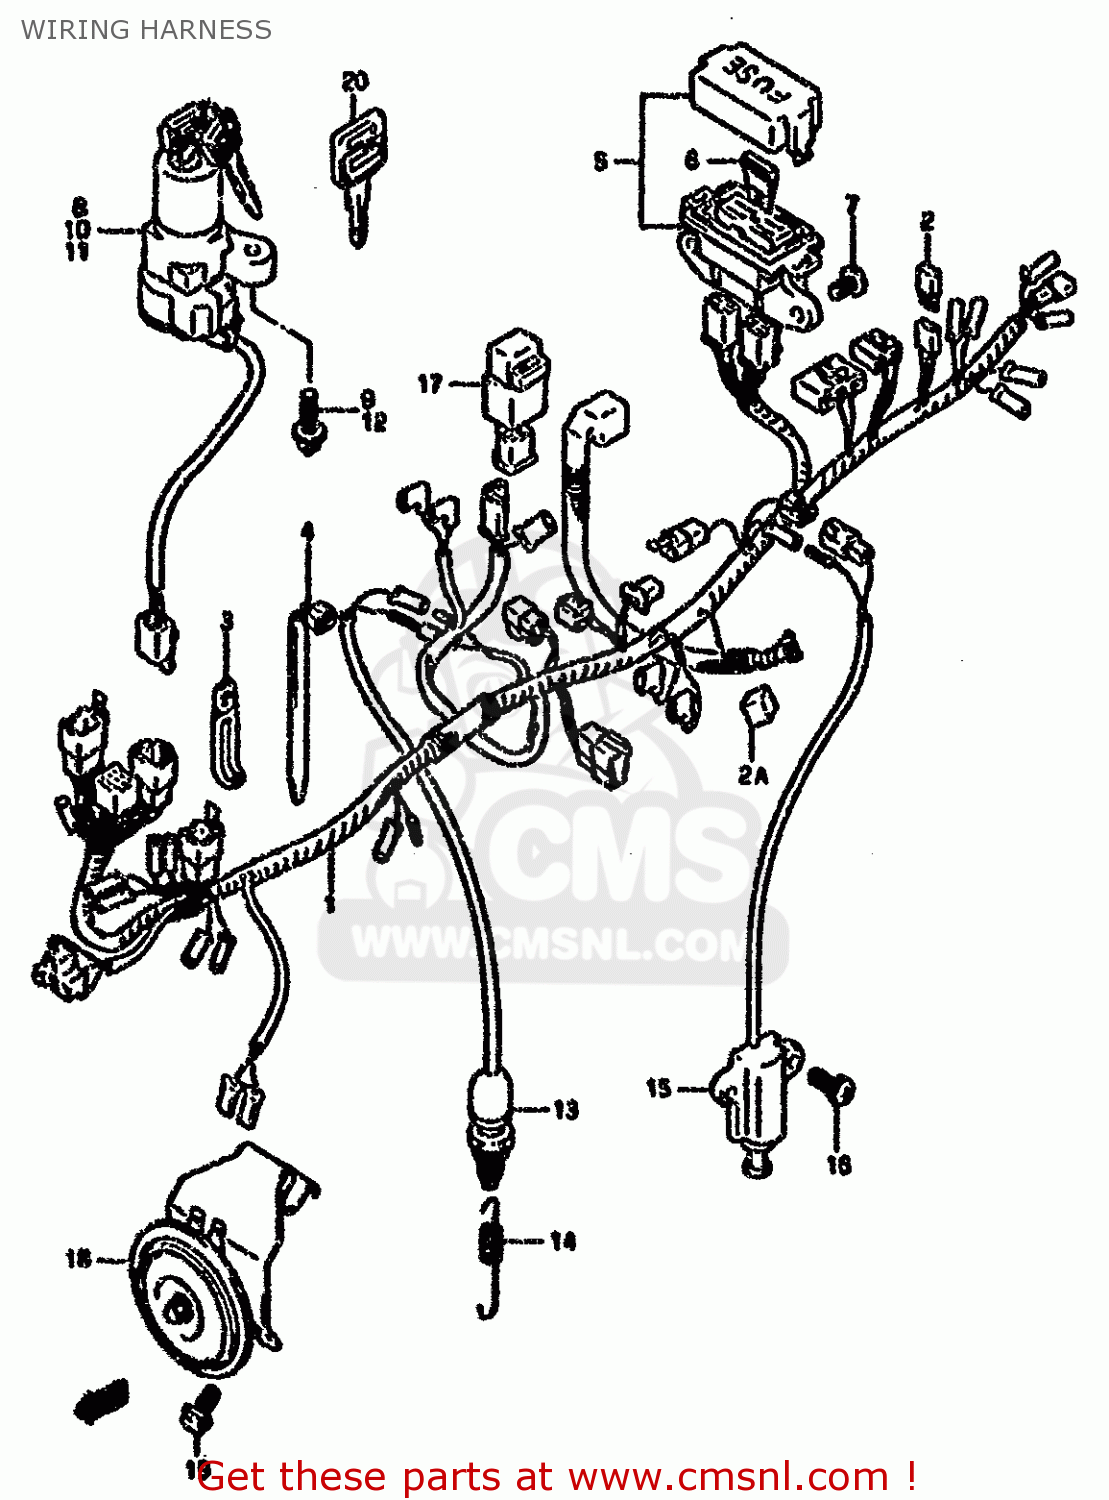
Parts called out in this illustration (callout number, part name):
1	HARNESS,WIRING
2	DIODE(STANLEY DE8804)
2A	CAP,BATTERY PLUS TERMINAL
3	CLAMP(L:45)
4	CLAMP L:165
5	BOX ASSY,FUSE
6	FUSE(10A)
7	SCREW 6X12
8	LOCK ASSEMBLY,STEERING
9	SCREW(6X18)
10	LOCK ASSEMBLY,STEERING
11	LOCK ASSEMBLY,STEERING
12	SCREW(6X18)
13	SWITCH ASSY,STOP LAMP
14	SPRING
15	SWITCH ASSY,SIDE STAND
16	BOLT
17	RELAY ASSY
18	HORN ASSEMBLY
19	BOLT
20	KEY,BLANK
